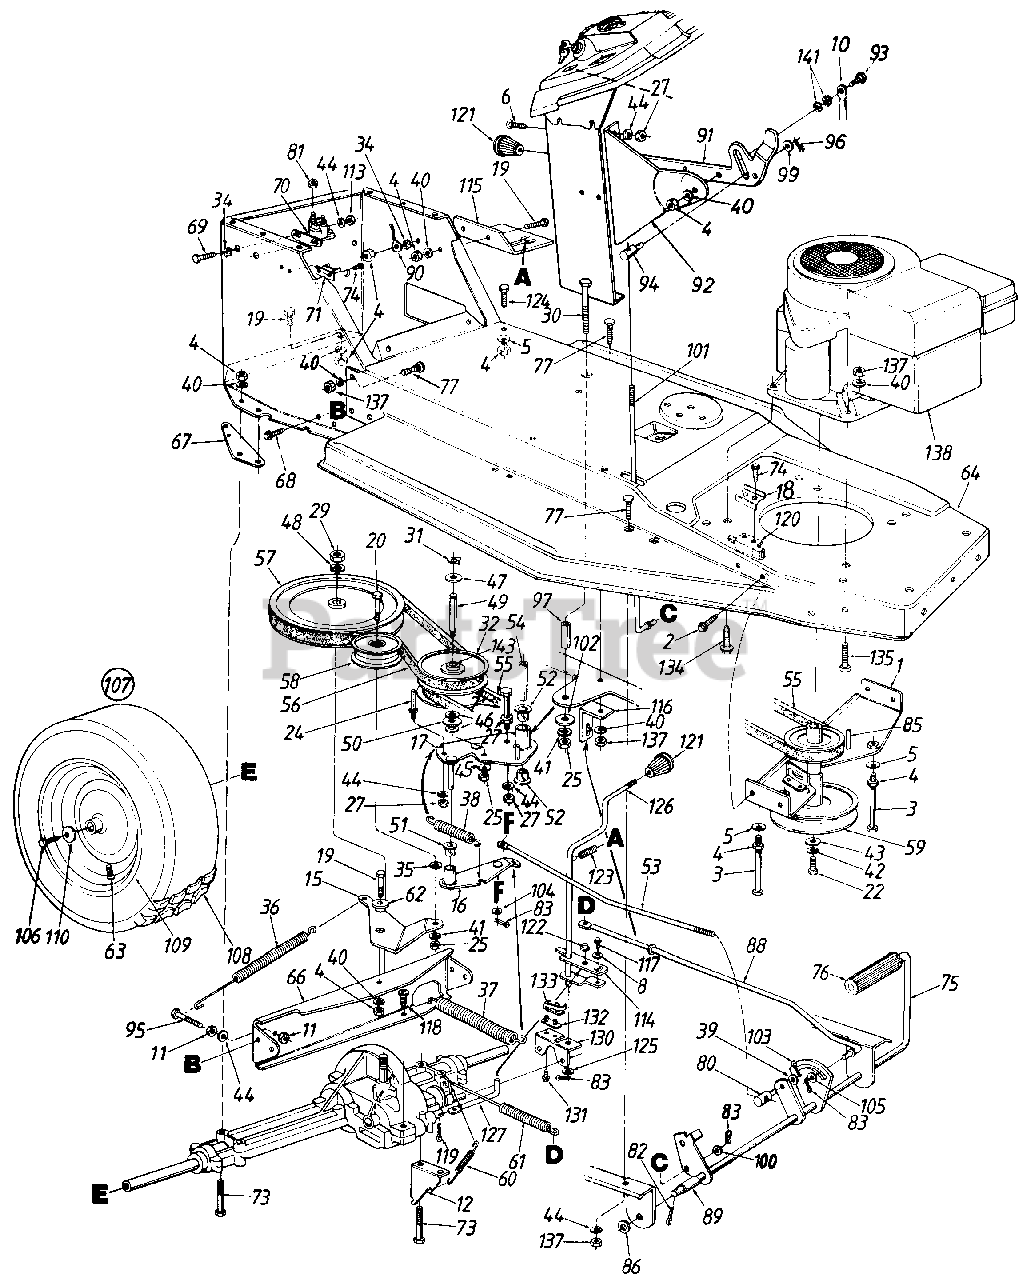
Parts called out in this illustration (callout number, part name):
1	Engine Pulley Belt Guard Ass'y.
2	Hex AB-Tap Scr. 1/4 x .62"
3	Hex Bolt 5/16-18 x 5 1/4" Lg.
4	Hex Nut 5/16-18 Thd.
5	Bell-Wash. .345" I.D. x .88
6	Truss-Mach. Scr. 1/4-20 x .50"
7	Hex Bolt 1/4-20 x 3.5" Lg.
8	Bell-Wash. .265" I.D. x .75
10	Speed Selector Brace
11	Hex Nut 1/4-28 thd.
17	Variable Speed Brkt. Ass'y.
18	Switch Plate
19	Hex Bolt 5/16-18 x .75" Lg.
20	Hex Bolt 3/8-24 x 2.0" Lg. Gr. 5
22	Hex Bolt 7/16-20 x 1.5" Lg.
24	Belt Guard Pin
25	Hex Nut 3/8-24 Thd.
27	Hex Nut 1/4-20 Thd.
29	Hex Jam Nut 9/16-18 Thd.
30	Hex Bolt 3/8-24 x 3.75" Lg.
31	Snap Ring
32	Variable Speed Pulley Ass'y.
34	Ext. L-Wash. 5/16" I.D.
35	Fl-Wash. 3/8" I.D. x 1.0" O.D.
36	Extension Spring 6.12" Lg.
37	Extension Spring 7.58" Lg.
38	Extension Spring 2.59" Lg.
39	Fl-Wash. .385" I.D. x .620"
40	L-Wash. 5/16" I.D.
41	L-Wash. 3/8" I.D.
42	L-Wash. 7/16" I.D.
43	Fl-Wash. .450" I.D. x 1.25"
44	L-Wash. 1/4" I.D.
45	Bell-Wash. .39" I.D. x 1.13"
46	Fl-Wash. .56" I.D. x 1.0" O.D.
47	Washer "Teflon" .565 I.D.
48	Bell-Wash. 9/16" I.D. x 1.125" O.D.
49	Shaft .56" Dia. x 3.875" Lg.
50	Thrust Brg. 1.25 O.D.
51	Flanged Nyliner Brg.
52	Nyliner Flanged Brg.
53	Speed Control Rod
55	V-Belt
56	V-Belt
57	V-Pulley 8" Dia.
58	Idler Pulley 3-1/8" Dia.
59	Dbl. Pulley 6.0" Dia. x 3.56"
60	Extension Spring 3.18" Lg.
61	Extension Spring 7.08" Lg.
62	Shld. Spacer .500" Dia.
63	Air Valve
66	Transaxle Support Brkt.
69	Hex Bolt 1/4-20 x .62" Lg.
70	Solenoid
71	Circuit Breaker
73	Hex Bolt 5/16-18 x 2.75" Lg.
74	Truss Mach. B-Tap Scr. #10 x .50" Lg.
77	Ribbed Neck Bolt 5/16-24 x .84"
80	Ferrule
81	Hex Sems Nut 1/4-20 Thd.
82	Cot-Pin 1/8" Dia. x 1.25" Lg.
83	Cot-Pin 3/32" Dia. x .75" Lg.
85	Sq. Key 1/4 x 2.0" Lg.
86	Fl-Wash. .635" I.D. x 1.0"
89	Spacer 5/8" I.D. x 1.2" Lg.
90	Ground Wire 7.25" Lg.
91	Speed Selector Lever
92	7 Speed Selector Brkt.
93	Shld. Bolt .437" Dia. x .47" Lg.
94	Ferrule
95	Hex Bolt 1/4-28 x 1.25" Lg.
96	Intern. Cot-Pin 5/16" Dia.
97	Spacer .375" I.D. x .625"
99	Fl-Wash. .344" I.D. x .62"
100	Fl-Wash. .25" I.D. x .62" O.D.
101	Speed Control Rod
102	Fl-Wash. 3/8" I.D. x 1.25" O.D.
103	Cot-Pin 1/8" Dia. x 1.0" Lg.
104	Fl-Wash. .34" I.D. x .68"
105	Fl-Wash. .34" I.D.
106	Hex L-Bolt 5/16-24 x .75" Lg.
110	Bell-Wash. .345" I.D. x .88"
113	Hex Jam Nut 1/4-20 Thd.
114	Shift Lever Adjusting Link
115	Shift Lever Spring Brkt.
118	Hex Wash. Hd. Tap Scr. 1/4-20 x .5" Lg.
119	Intern. Cotter Pin
120	Safety Switch (Clutch)
121	Knob
122	Retaining Ring
123	Compression Spring 1.5" Lg.
124	Hex Wash. Hd. Scr. 5/16-18 x .62" Lg.
125	Fl-Wash. .469" I.D. x .88"
130	Shift Lever Support
131	Hex Wash. Hd. #8 x .50" Lg.
132	Insulator Nut Plate
133	Spring Switch
134	Hex Tap Scr. 3/8-16 x 1.25"
135	Hex Bolt 5/16-24 x 1 1/4" Lg. Gr. 5
137	Hex Nut 5/16-24 Thd.
138	Engine
141	Wave Wash. .445" I.D.
